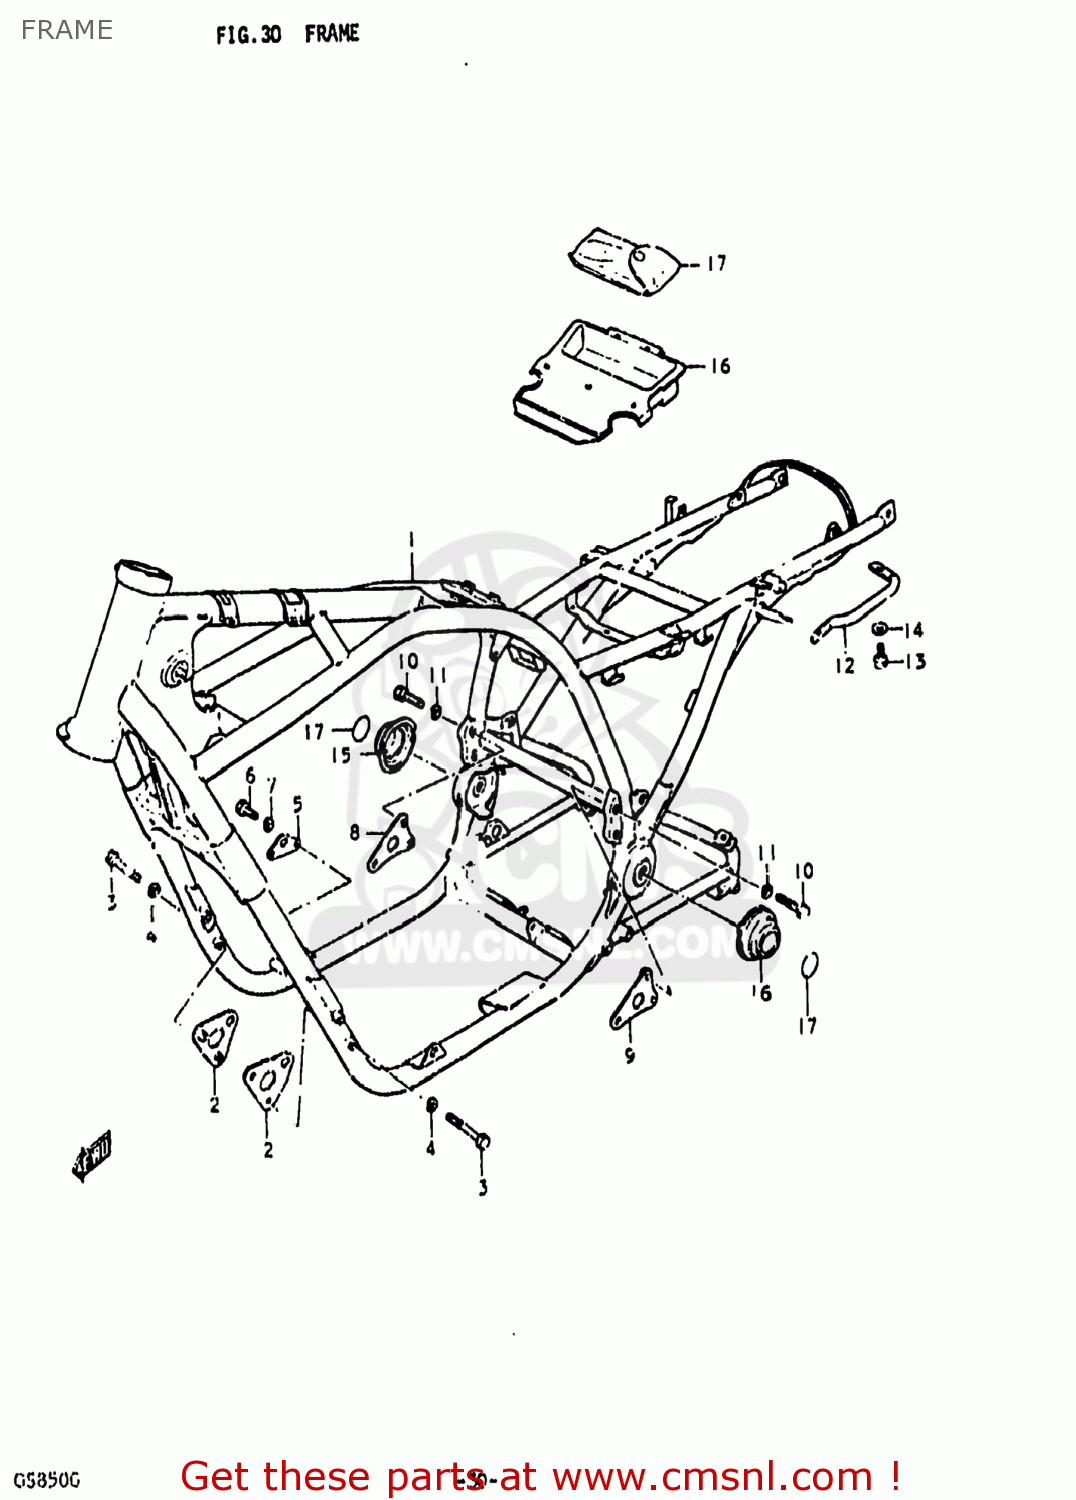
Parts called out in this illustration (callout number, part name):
1	FRAME
2	PLATE,ENGINE MOUNTING
3	BOLT
4	LOCK WASHER
5	PLATE,ENGINE MOUNTING
6	BOLT
7	LOCK WASHER
8	PLATE,ENGINE MOUNTING
9	PLATE,ENGINE MOUNTING
10	BOLT 8X40
11	LOCK WASHER
12	GRIP,FRAME
13	BOLT
14	WASHER
15	COVER,REAR SWING ARM PIVOT
16	COVER,REAR SWING ARM PIVOT
17	EMBLEM,FRAME COVER
18	HOLDER,TOOL
19	TOOL SET
